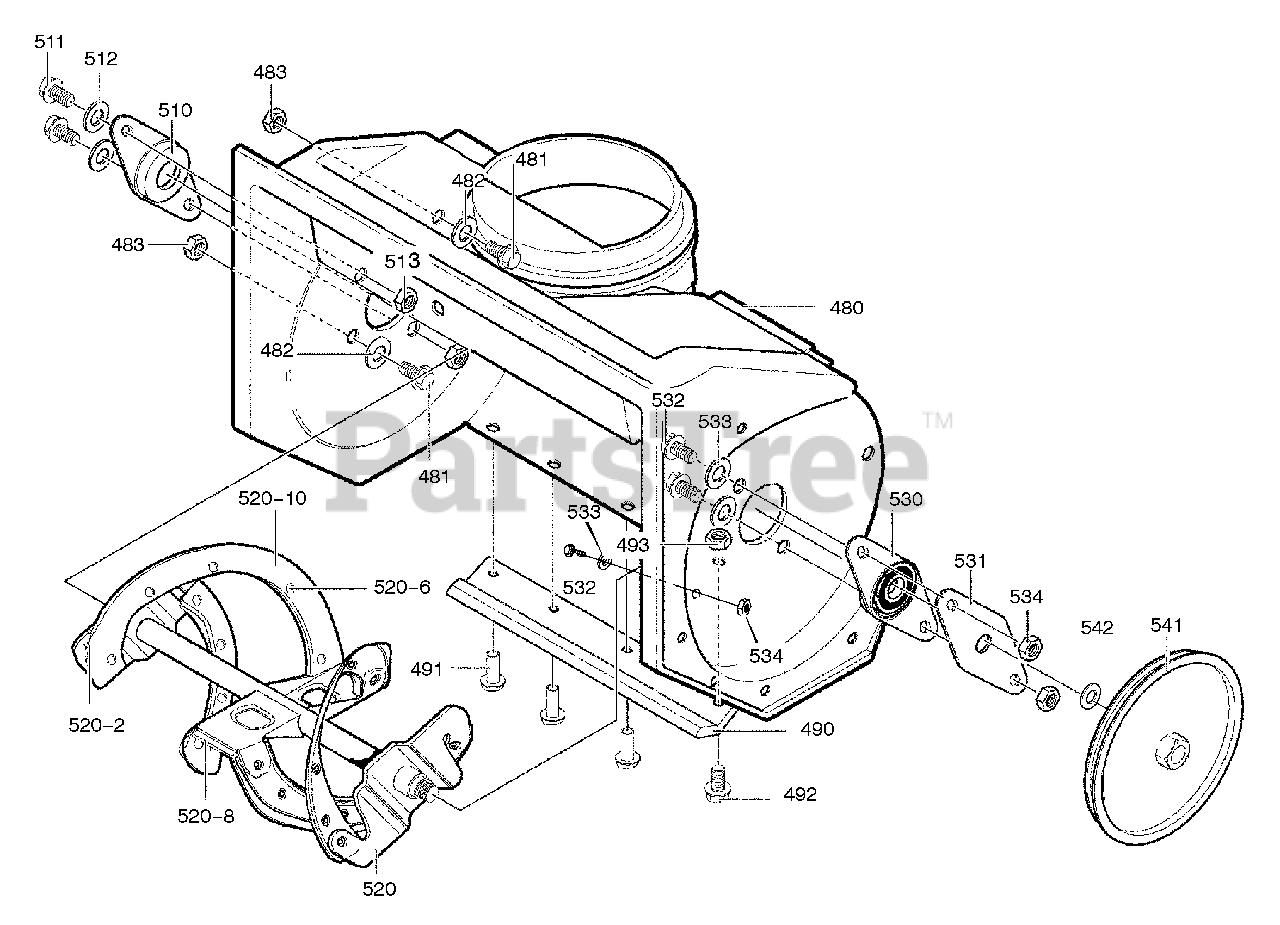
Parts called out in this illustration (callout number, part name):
480	HOUSING, ASSEMBLY
481	SCREW, 1/4-20 X .75
482	WASHER, FLAT .281 X .63 X .065
483	NUT, HEX 1/4-20 YZ
490	BLADE, SCRAPER
491	RIVET, OVSET
492	SCREW, 1/4-20 X .75
493	NUT, 1/4-20 YZ
510	BEARING, FLANGE
511	SCREW, 1/4-20 X 1.00
512	WASHER, FLAT .281 X .63X.065
513	NUT, 1/4-20
520	AUGER, ASSY
520-2	BLADE, AUGER
520-8	BLADE, CENTER
520-10	AUGER & BLADE SUPPORT
530	BEARING & PLATE ASSEMBLY
531	PLATE, RETAINER
532	SCREW, 1/4-20 X .63
533	WASHER, FLAT .281X.63 X .065
534	NUT, 1/4-20
